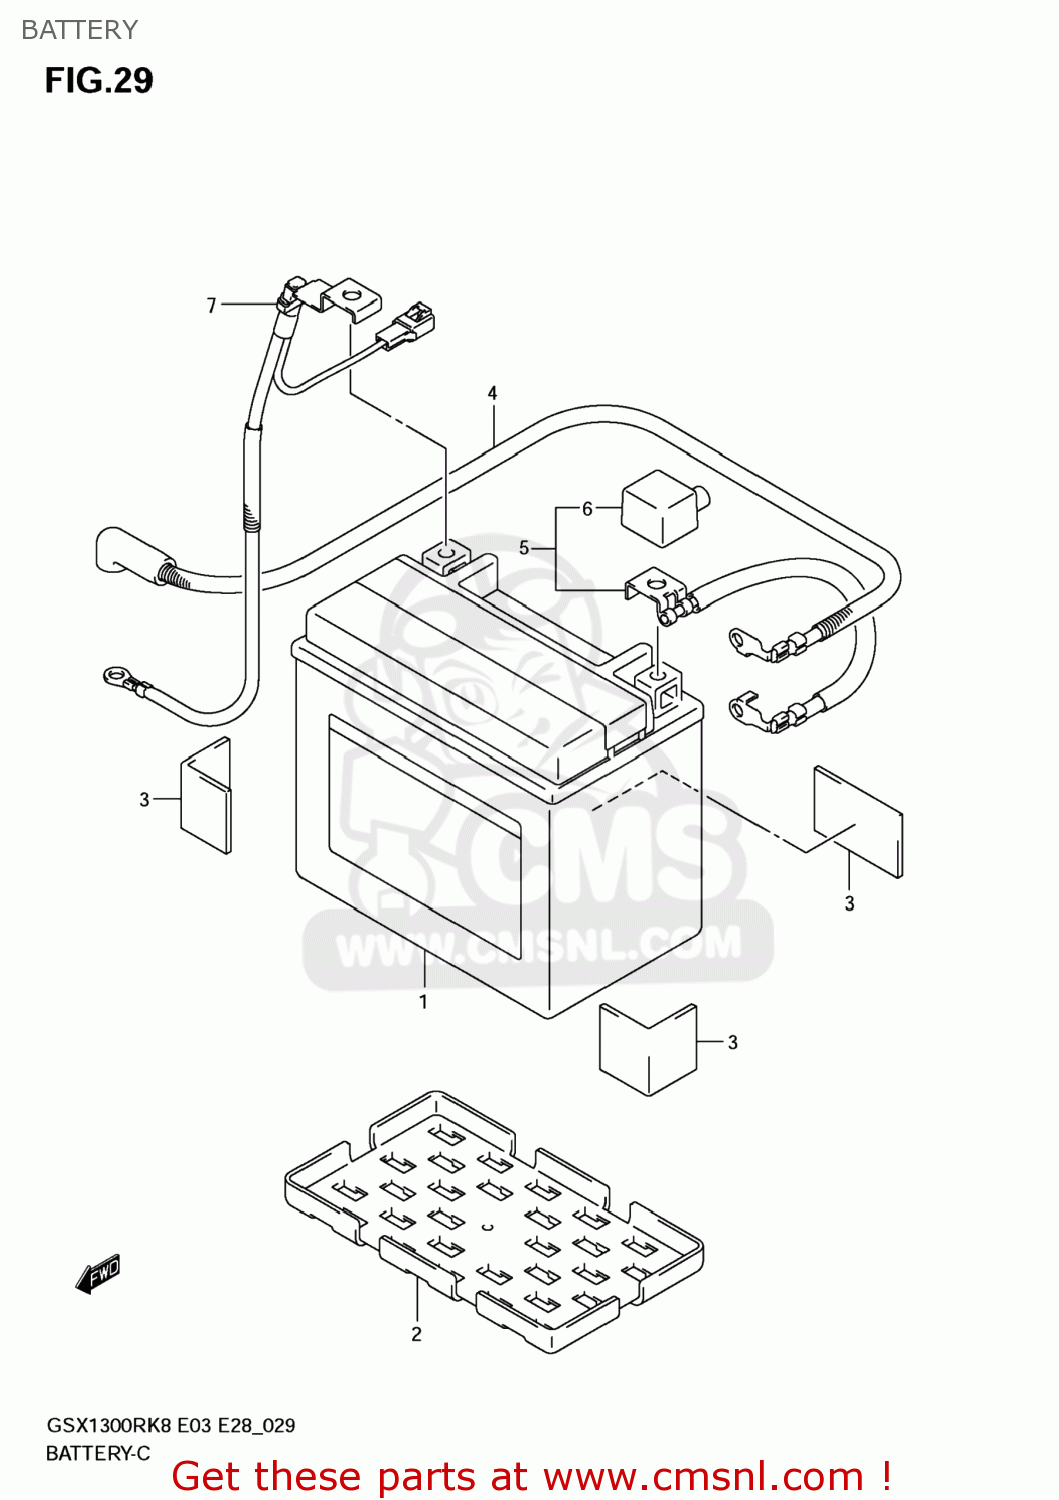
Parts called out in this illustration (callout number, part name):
1	BATTERY ASSY(YTX12-BS,12V10AH)
2	PROTECTOR,BATTERY
3	CUSHION(30X50X3)
4	WIRE,STARTER MOTOR LEAD
5	WIRE,BATTERY PLUS LEAD
6	CAP,BATTERY PLUS
7	WIRE,BATTERY MINUS LEAD
